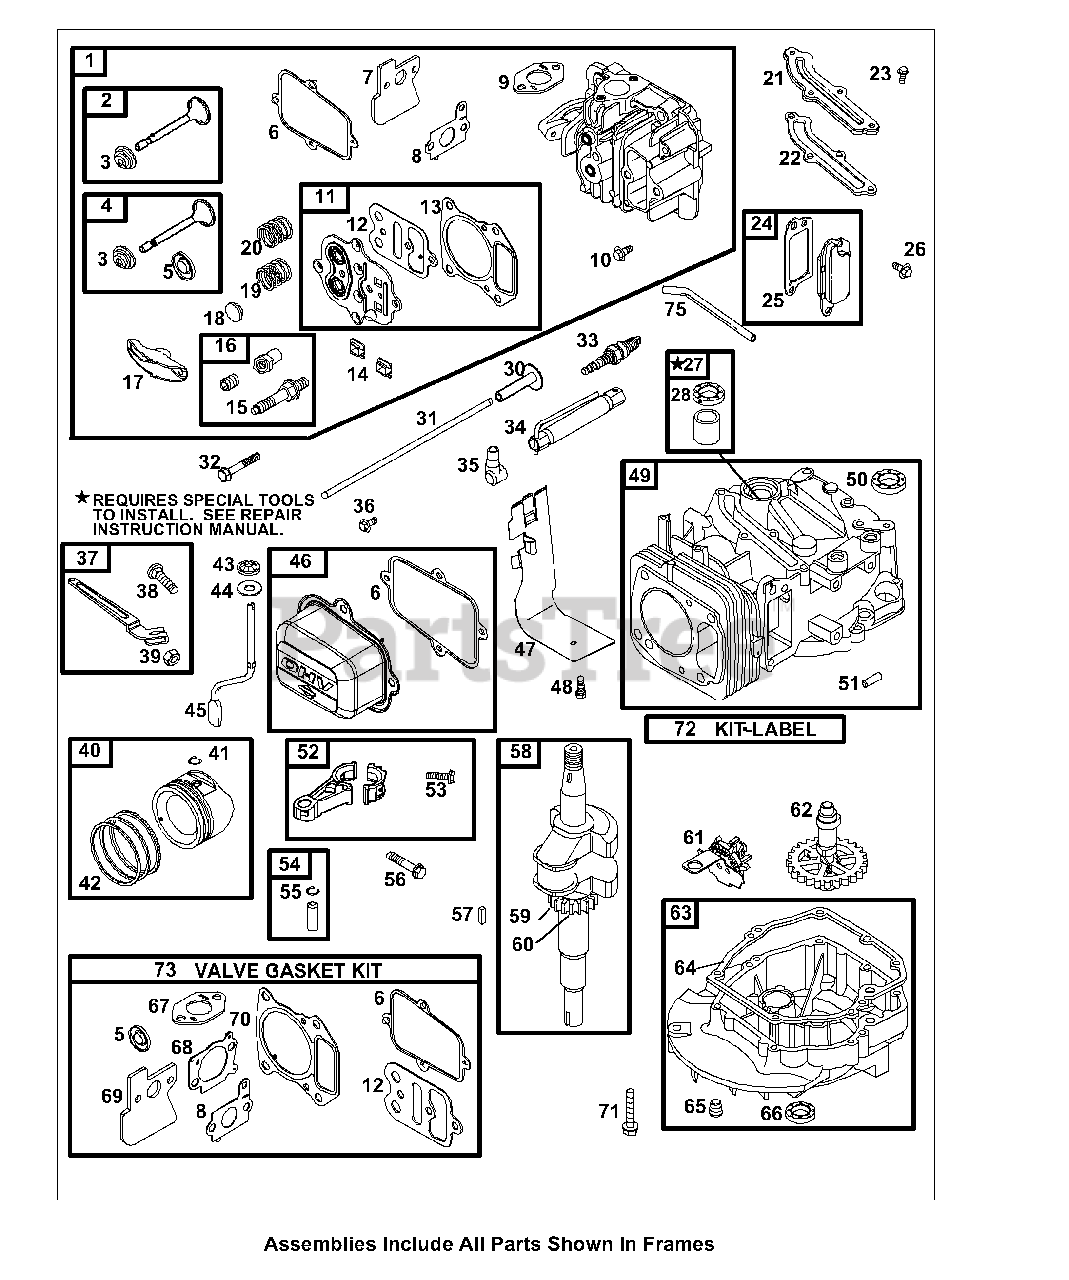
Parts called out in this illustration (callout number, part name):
1	Head-Cylinder
2	Valve-Exhaust
3	Retainer-Valve
4	Valve-Intake
5	Seal-Valve
6	Gasket-Rocker Cover
7	Spacer-Carburetor
8	Gasket-Intake
9	Gasket-Exhaust
10	Screw (Cylinder Head Plate)
11	Gasket Kit-Cylinder Head/Plate
12	Gasket-Cylinder Head Plate
13	Gasket-Cylinder Head
14	Guide-Push Rod
15	Stud (Rocker Arm)
16	Ball-Rocker Arm
17	Arm-Rocker
19	Spring-Valve (Intake)
20	Spring-Valve (Exhaust)
21	Cover-Breather Passage
22	Gasket-Breather Passage
23	Screw (Breather Passage Cover)
24	Breather Assembly
25	Gasket-Breather
26	Screw (Breather Assembly)
27	Kit-Bushing/Seal
28	Oil Seal (Magneto Side)
30	Tappet-Valve
31	Rod-Push
32	Screw (Cylinder Head)
33	Spark Plug
34	Wrench-Sparkplug
35	Boot-Sparkplug
36	Screw (Rocker Cover)
37	Lever-Governor Control
38	Bolt (Governor Control Lever)
39	Nut (Governor Control Lever)
40	Piston Assembly
41	Piston Pin Lock
43	Retainer-Governor Shaft
44	Washer (Governor Crank)
45	Crank-Governor
46	Cover-Rocker
47	Shield-Cylinder
48	Screw (Cylinder Shield)
49	Cylinder Assembly
50	Oil Seal (Magneto Side)
51	Pin-Locating
52	Rod-Connecting
53	Screw (Connecting Rod)
54	Piston Pin
55	Piston Pin Lock
56	Screw (Connecting Rod)
57	Key-Flywheel
58	Crankshaft
59	Gear-Timing
60	Key-Timing
61	Slinger-Governor/Oil
63	Sump-Engine
64	Gasket-Crankcase
65	Plug-Oil Drain
66	Seal-Oil (PTO Side)
67	Gasket-Exhaust
68	Gasket-Air Cleaner
69	Spacer-Carburetor
70	Gasket-Cylinder Head
71	Screw (Engine Sump)
73	Kit-Valve Gasket
75	Tube-Breather
